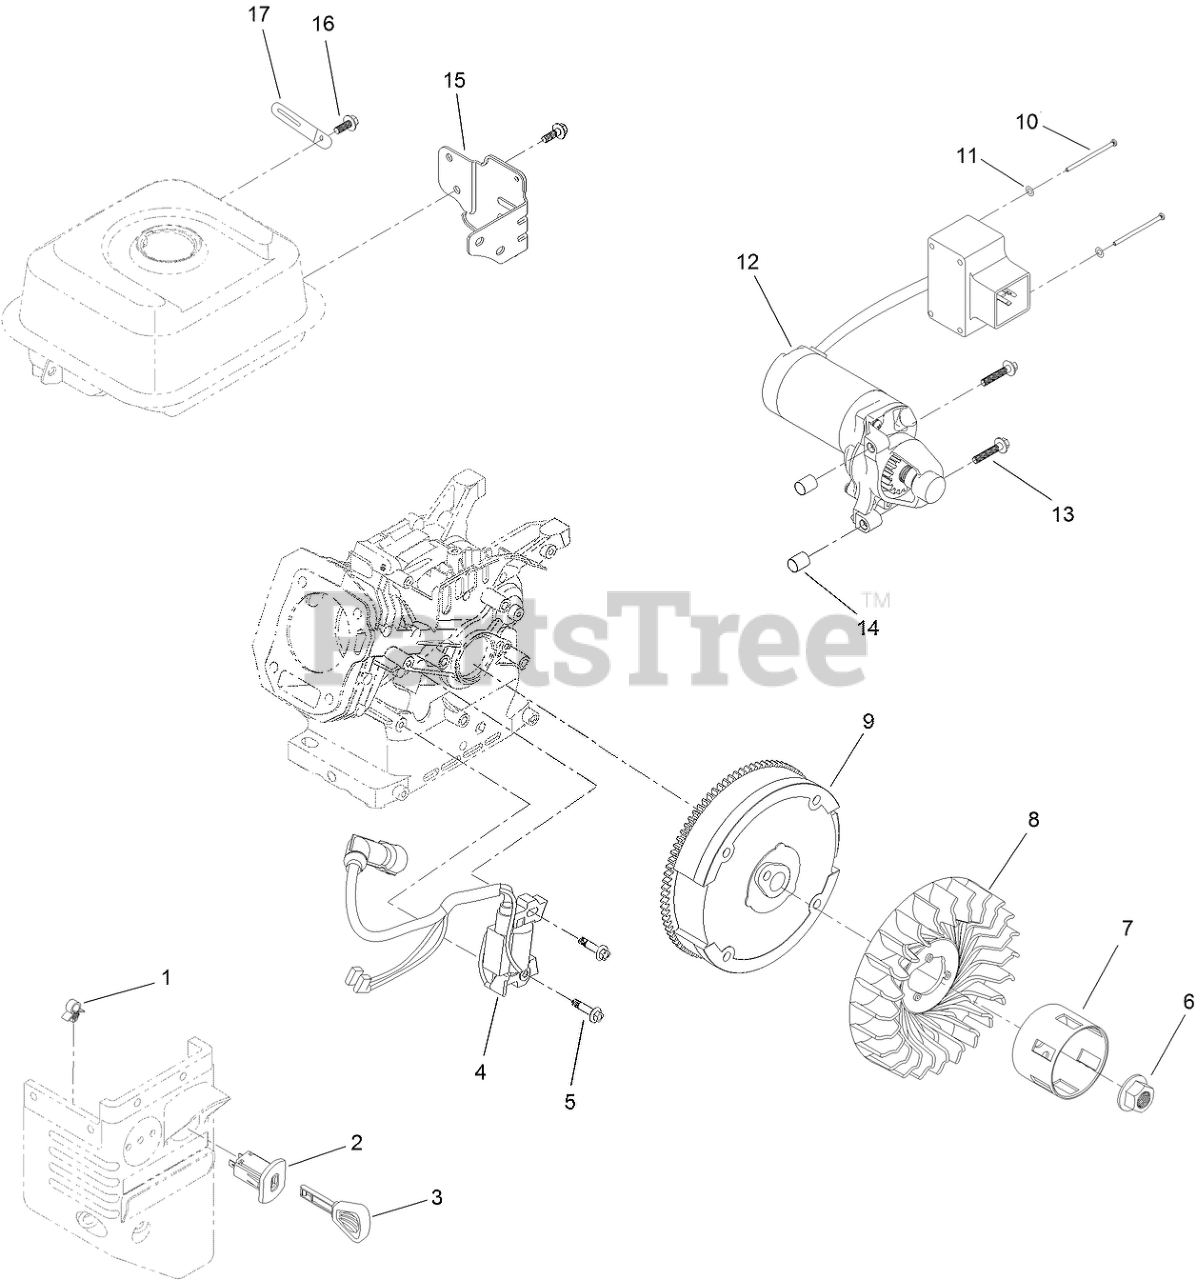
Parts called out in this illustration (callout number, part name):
2	SWITCH-KEY
4	IGNITION COIL ASM
5	SCREW-HHF
6	NUT-FLANGE
7	CUP-STARTER
9	FLYWHEEL
10	SCREW-BHP
11	WASHER-PLAIN
12	MOTOR-STARTER
13	SCREW-FLANGE
14	PIN-DOWEL
15	BRACKET-BOX, SWITCH
16	SCREW-HHF
17	CLIP-HARNESS, WIRE
